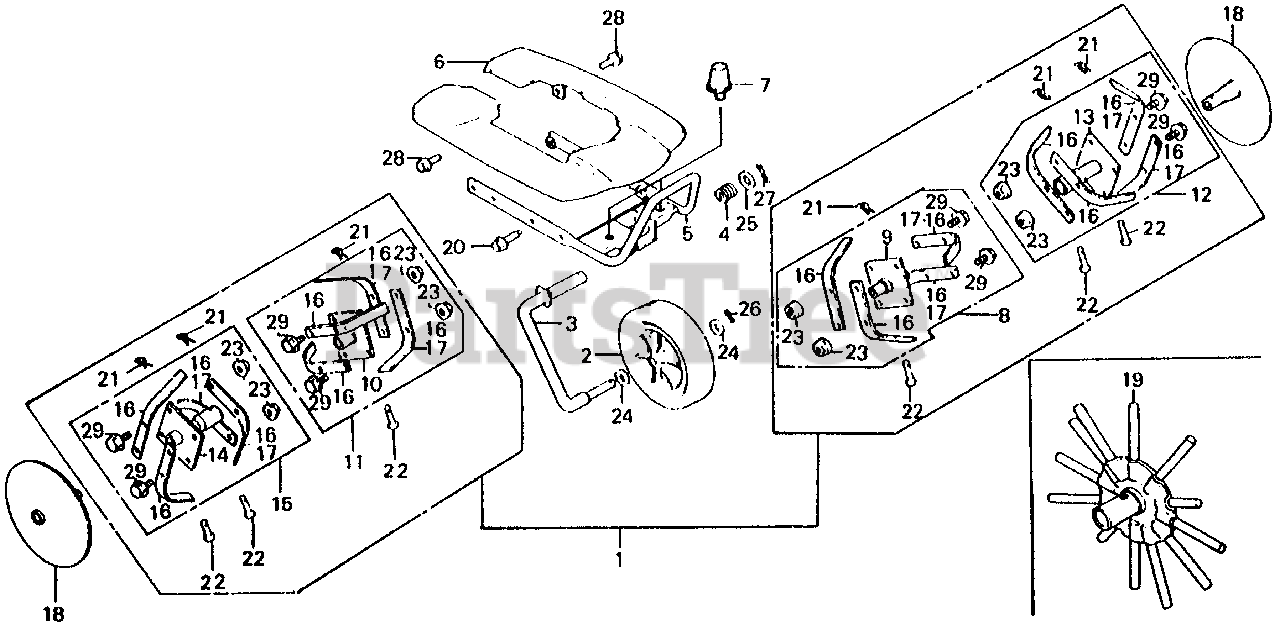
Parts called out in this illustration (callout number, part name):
1	ROTOR KIT *NH1*
2	WHEEL, RR. (7")
3	BAR, FR. WHEEL
4	SPRING, FR. WHEEL
5	PIPE, FR. GUARD *NH105* (MAT BLACK)
6	FENDER *NH31* (MCKINLEY WHITE)
7	DAMPER, RUBBER
8	PIPE, L. MAIN *NH1* (BLACK)
9	PIPE, L. ROTOR MAIN
10	PIPE, R. ROTOR MAIN
11	PIPE, R. MAIN *NH1* (BLACK)
12	PIPE, L. EXTENSION *NH1* (BLACK)
13	PIPE, L. ROTOR EXTENSION
14	PIPE, R. ROTOR EXTENSION
15	PIPE, R. EXTENSION *NH1* (BLACK)
16	TINE A, ROTOR
17	TINE A, ROTOR
18	DISK, SIDE *NH1* (BLACK)
19	ROTOR, PICK-UP
20	BOLT, FLANGE (6X12) (CT200)
20	BOLT, FLANGE (6X16)
21	PIN, SNAP (7MM)
22	PIN, WHEEL (8X35)
23	NUT, FLANGE (8MM)
24	WASHER, PLAIN (12MM)
25	WASHER, PLAIN (18MM)
26	PIN, COTTER (3.0X45)
27	PIN, COTTER (3.0X45)
28	BOLT, FLANGE (6X12)
29	BOLT, FLANGE (8X20)
